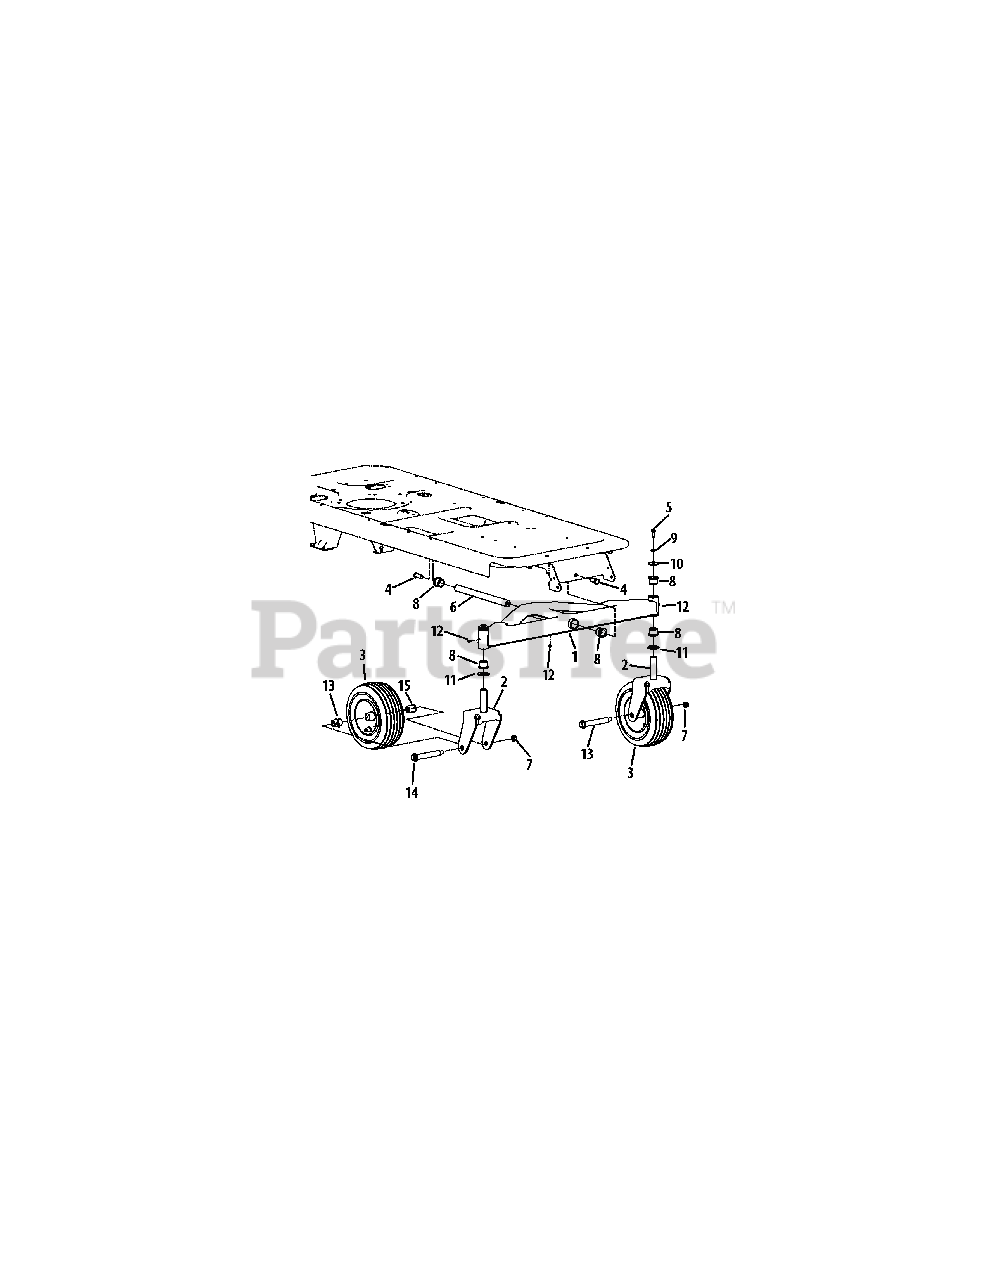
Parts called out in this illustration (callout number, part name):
1	Front Pivot Axle
2	Castor Wheel Bracket
3	Wheel Assembly, 11.0 x 4.0 x 5.0
4	Hex Lock Screw, 1/2-13 x 1.25
5	Hex Cap Screw, 3/8-16 x 1.0
6	Axle Shaft
7	Hex Lock Nut, 1/2-13
8	Flange Bearing, 1.0 x 1.246
9	Lock Washer, 3/8
10	Flat Washer, .39 x 1.5 x .134
11	Flat Washer, 1.0 x 1.75 x .107
12	Lube Fitting, 3/16 Drive
13	Shoulder Screw, .75 x 4.75 x 7/16-14
14	Flange Bearing, .76 x 1.0 x 1.2
15	Flange Bearing, .76 ID w/ Lube Ftg.
